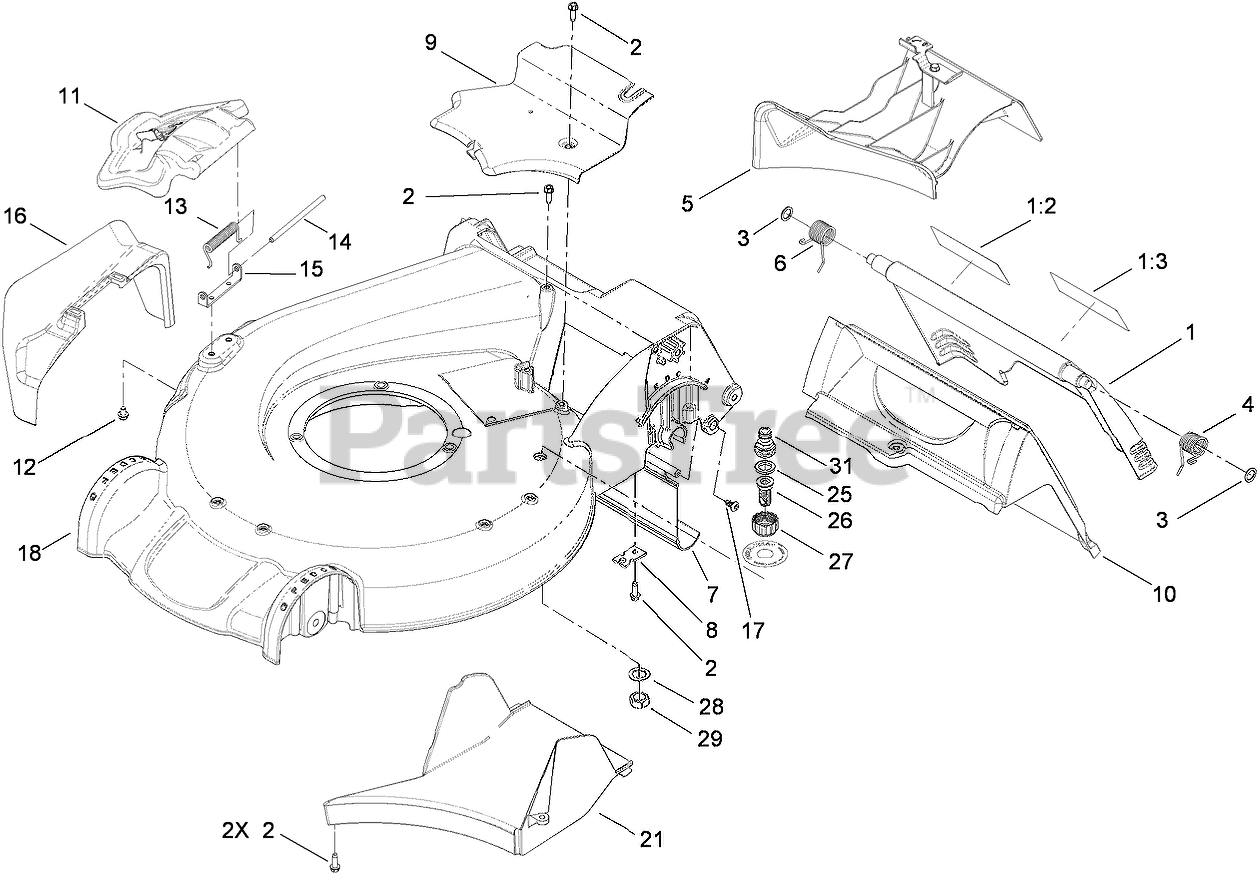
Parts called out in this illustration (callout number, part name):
1	REAR DOOR ASM
1:2	DECAL-WARNING
1:3	DECAL-WARNING
2	SCREW-HWHTF
3	WASHER-NYLON
4	SPRING-TORSION
5	MULCH PLUG ASM
6	SPRING-TORSION
7	SHIELD-TRAILING
8	BRACKET-CABLE, TRACTION
9	COVER-BELT
11	DISCHARGE DOOR ASM
12	SCREW-HWH
13	SPRING-TORSION
14	ROD-COVER
15	BRACKET-COVER
16	CHUTE-DISCHARGE, SIDE
17	SCREW-PTH
18	HOUSING ASM
21	TUNNEL-DISCHARGE
25	WASHER-SEAL, WASHOUT PORT
26	PORT-WASHOUT
27	COUPLING-HOSE, WASHOUT PORT
28	WASHER-TOOTH, INTERNAL
29	NUT-JAM
31	ADAPTER-CONNECT, QUICK
